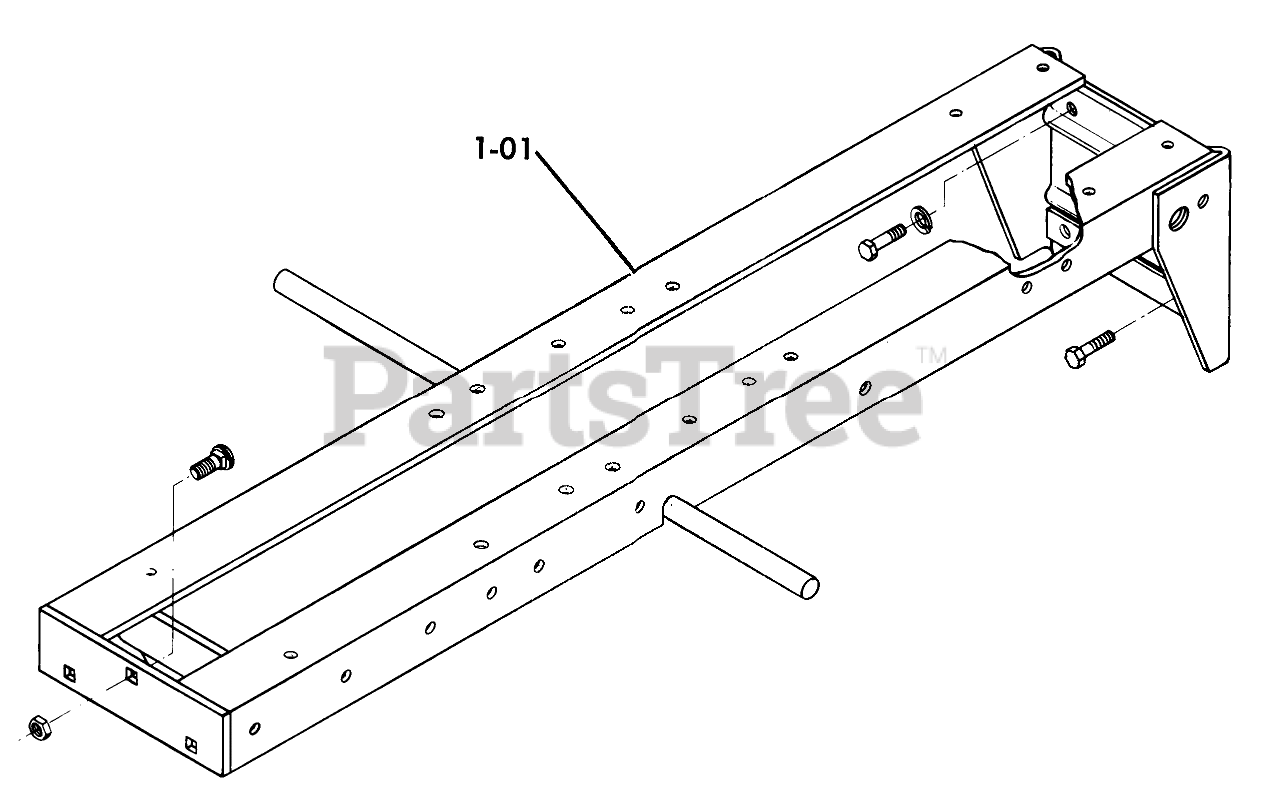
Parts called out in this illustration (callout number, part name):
1-01	Assy-Frame
1-01	Bolt
1-01	LOCKWASHER
1-01	Nut
